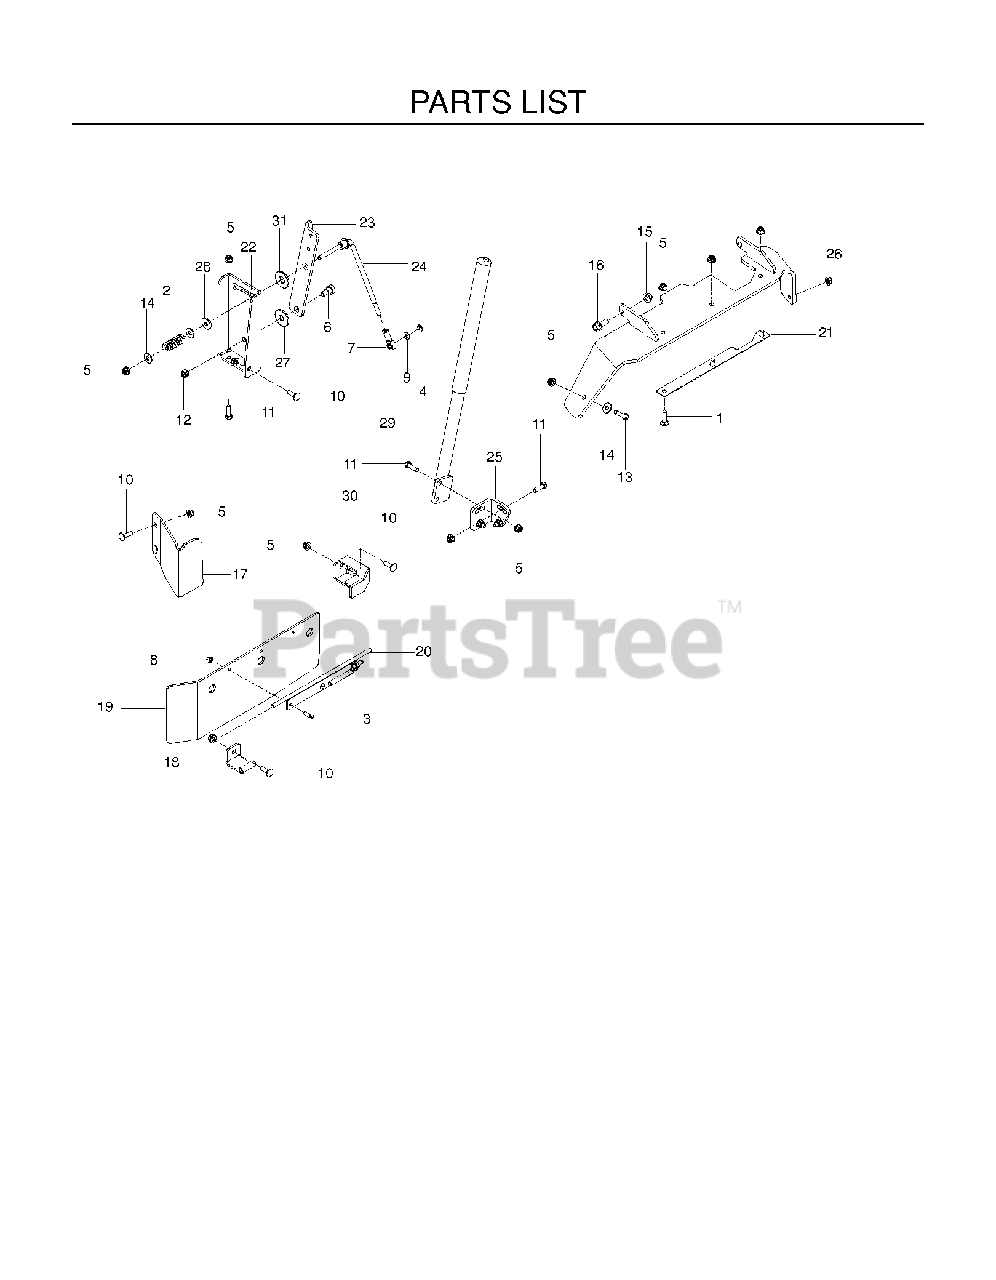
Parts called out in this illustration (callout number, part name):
1	BOLT, CARRIAGE 5/16X1-1/4
3	SCR 1/4-20X3/4 SLTD RDHD GR2ZD
4	RING RETAINING EXT 5/16
5	5/16-18 NYLOC FLANGE NUT
6	SB 3/8-16 X 3/8 SKT HD ZD
7	RH ROD END
8	NUT 1/4-20 NYLOC
9	FLAT WASHER 5/16 SAE
10	RHSNB 5/16C X 1
11	HCS 5/16C X 1
12	NUT 3/8C CENTERBLOCK
13	HCS 5/16C X 1 1/4
14	WASHER 5/16 FLAT
15	NUT 3/8-16 HEX FLG NYLOC ZD
17	PLATE BLOCKER BLACK
18	WELDMT, PIVOT MTG
19	GATE - 54 BLACK
19	GATE - 60 BLACK
20	WELDMT, HINGE PLATE
21	PLATE REINFORCEMENT
22	MOUNTING BRACKET WLDT BLACK
23	LINKAGE, MAIN BLACK
24	LINK, GATE PIVOT
25	BRACKET, HANDLE SWIVEL BLK
26	CHUTE MTG WLDT
27	WASHER, FRICTION 1/2 NOM I.D.
28	WASHER, FRICTION 5/16 NOM I.D.
29	ASSEMBLY, HANDLE W/GRIP
30	WELDMT, PIVOT GUARD
31	WASHER, FRICTION 5/8 NOM I.D.
